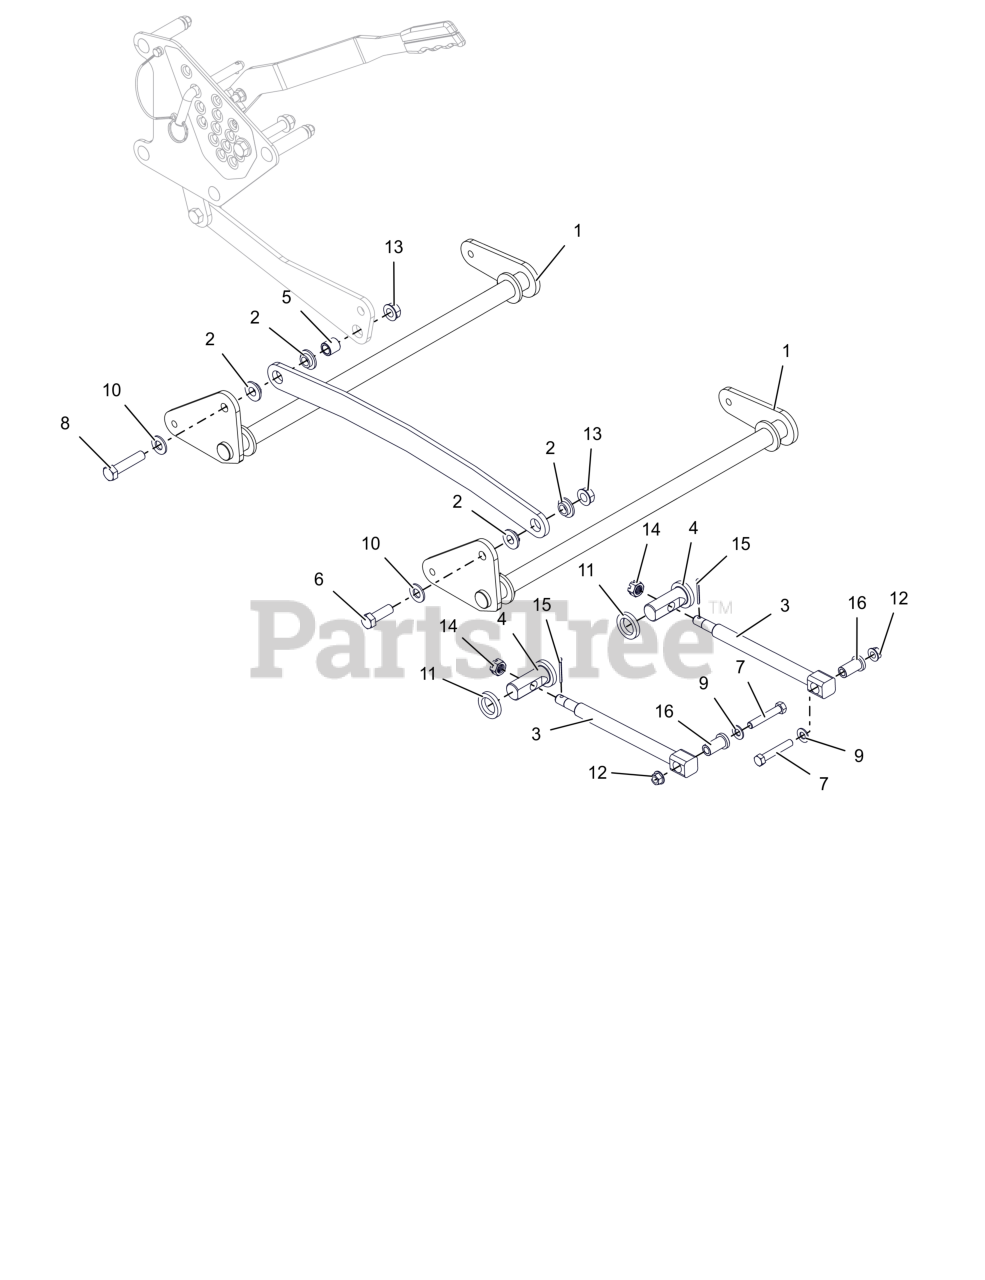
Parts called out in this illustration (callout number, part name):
1	WLDMT-32" DECK LIFT SHAFT(BLK)
2	BSHG-FLG .515X.750X.310X1.120
3	DRAG,LINK-HD
4	PIN, DECK LIFT
5	BSHG, SLV .510 X .751 X .750
6	BLT,HEX .50-13X1.50 G5 ZCC
7	BLT,HEX .38-16X2.25 G5 ZCC
8	BLT, HEX .50-13X2.25 G5 ZCC
9	WSHR-FL-STL 0.406X0.812X0.065 UNPLATED
10	WSHR,FLT .531X1.062X.095 ZCC
11	WSHR-FL-STL 1.0X1.50X.25
12	NUT-LK-CTR-FLG .375-16 GF ZCC
13	NUT-LK-CTR-FLG .500-13 GG ZCC
14	NUT-SL .50-13
15	PIN,CTR.12X1.25EXTPRSQCT ZC120
16	SPCR, DRAG LINK
